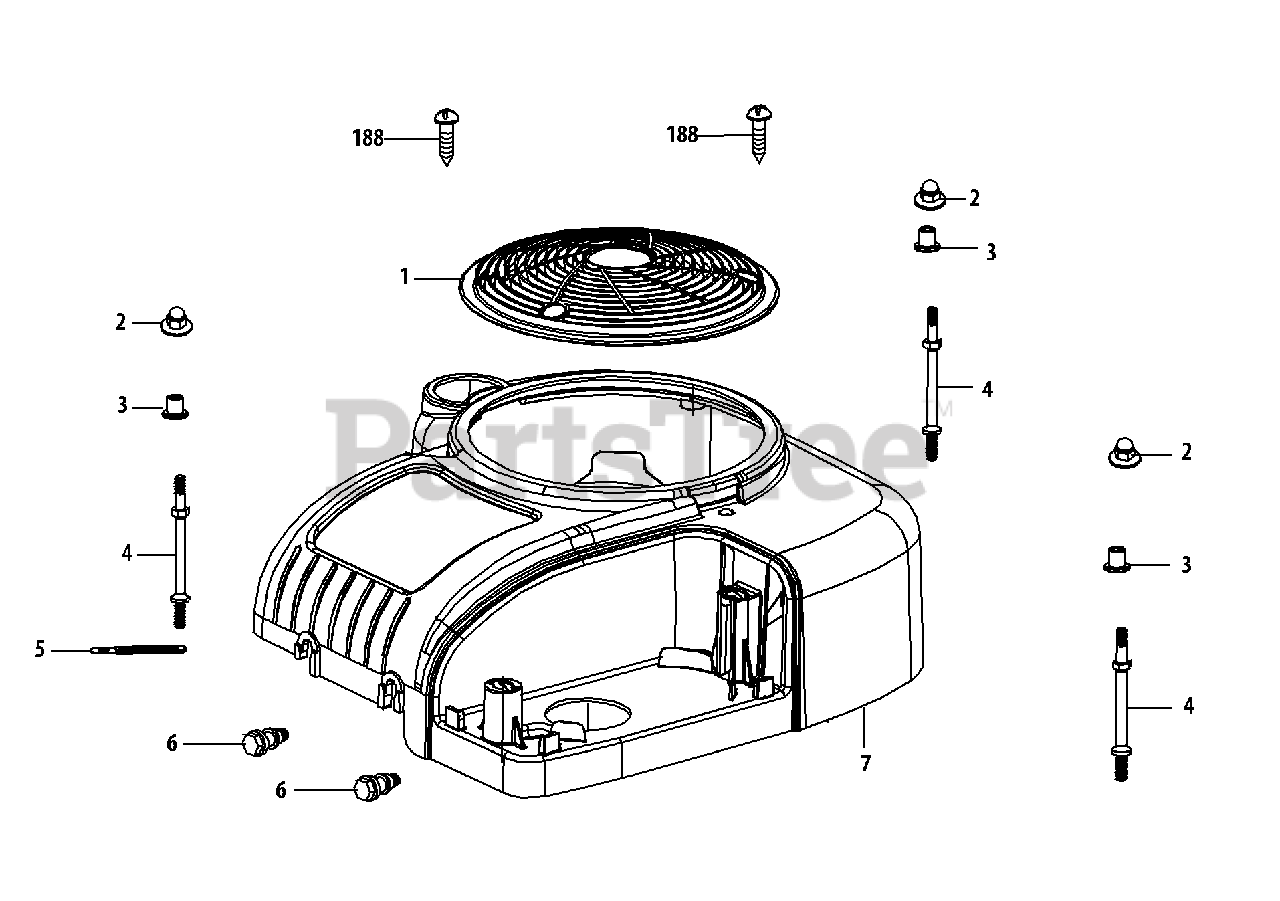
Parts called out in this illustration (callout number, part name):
1	Debris Shield
3	Engine Shroud Spacer
4	Starter / Shroud Stud M6×99
5	Flexible Clamp
6	Hook Bolt
7	Air Shield
188	Self-Tapping Bolt 5.5×25
